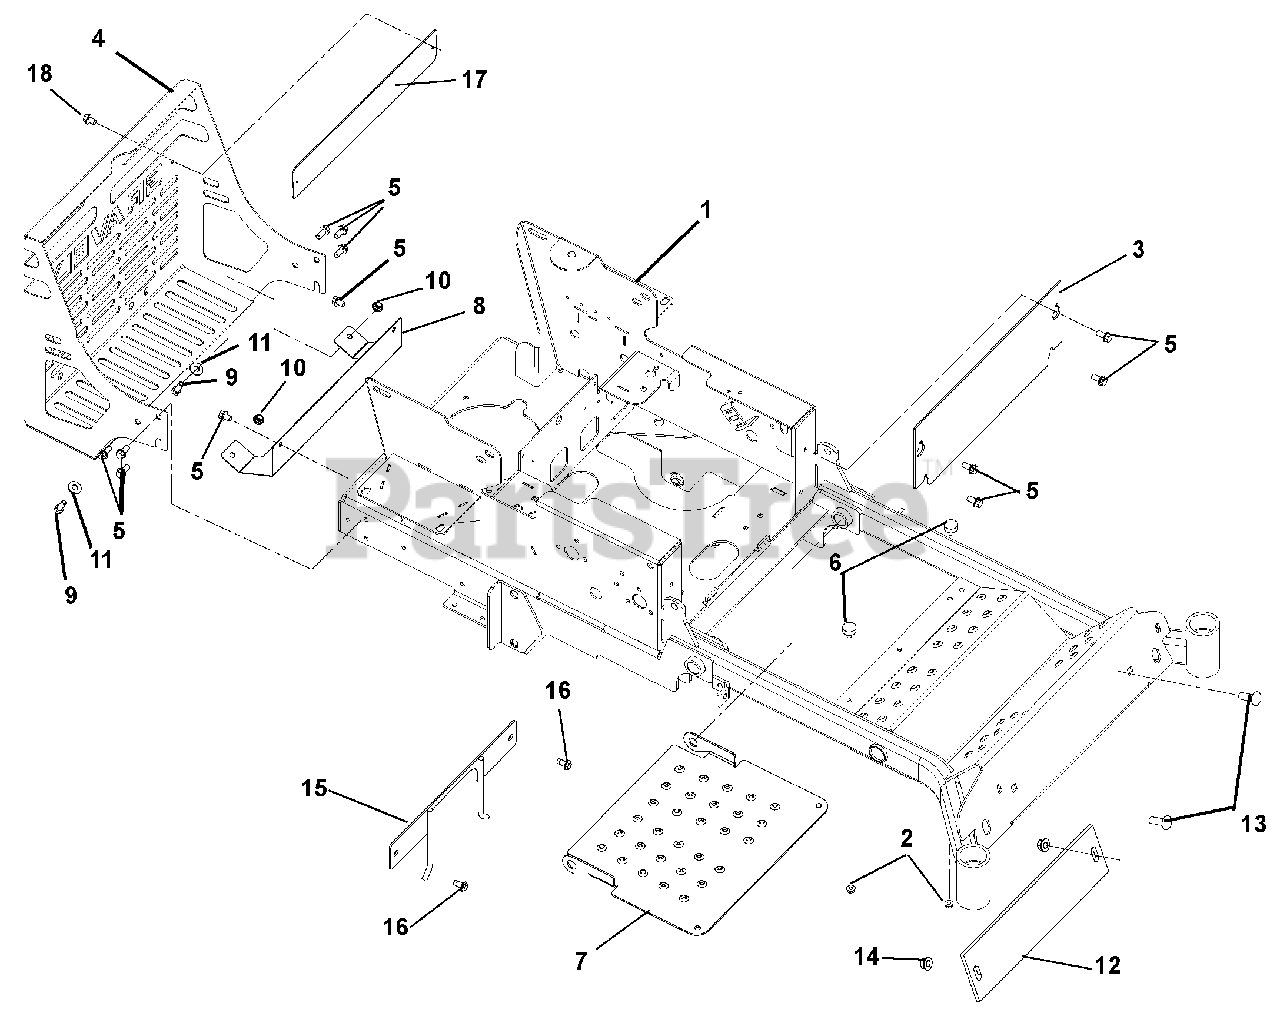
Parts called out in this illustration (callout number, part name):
1	Weldment, 48" Head Frame (068)
2	Nut, Spin Lock Flange .312-18
3	Kick Plate
4	Bumper, Max Zoom
5	Screw, Tapping .38-16 x .75 Hex Washer Head
6	Bumper, Rubber
7	Panel, Inspection
8	Heat Shield
9	Bolt, Hex .38-16 x 1.00 Grade 5
10	Nut, Nyloc Flange .38-16
11	Washer, Flat Steel .438 x 1.00 x .083
12	Counterwieght CZ Front- Red (068)
13	Bolt, Round Head Square Neck .50-13 x 2.25 Grade 5 (068)
14	Nut .50-13 Nyloc Flange (068)
15	Weldment, PTO Belt Finger
16	Screw, Tapping .38-16 x .75 Hex Washer Head Thread
17	Bumper Backer Plate
18	Screw, Tapping .25-20 x .50 Hex Washer Head
